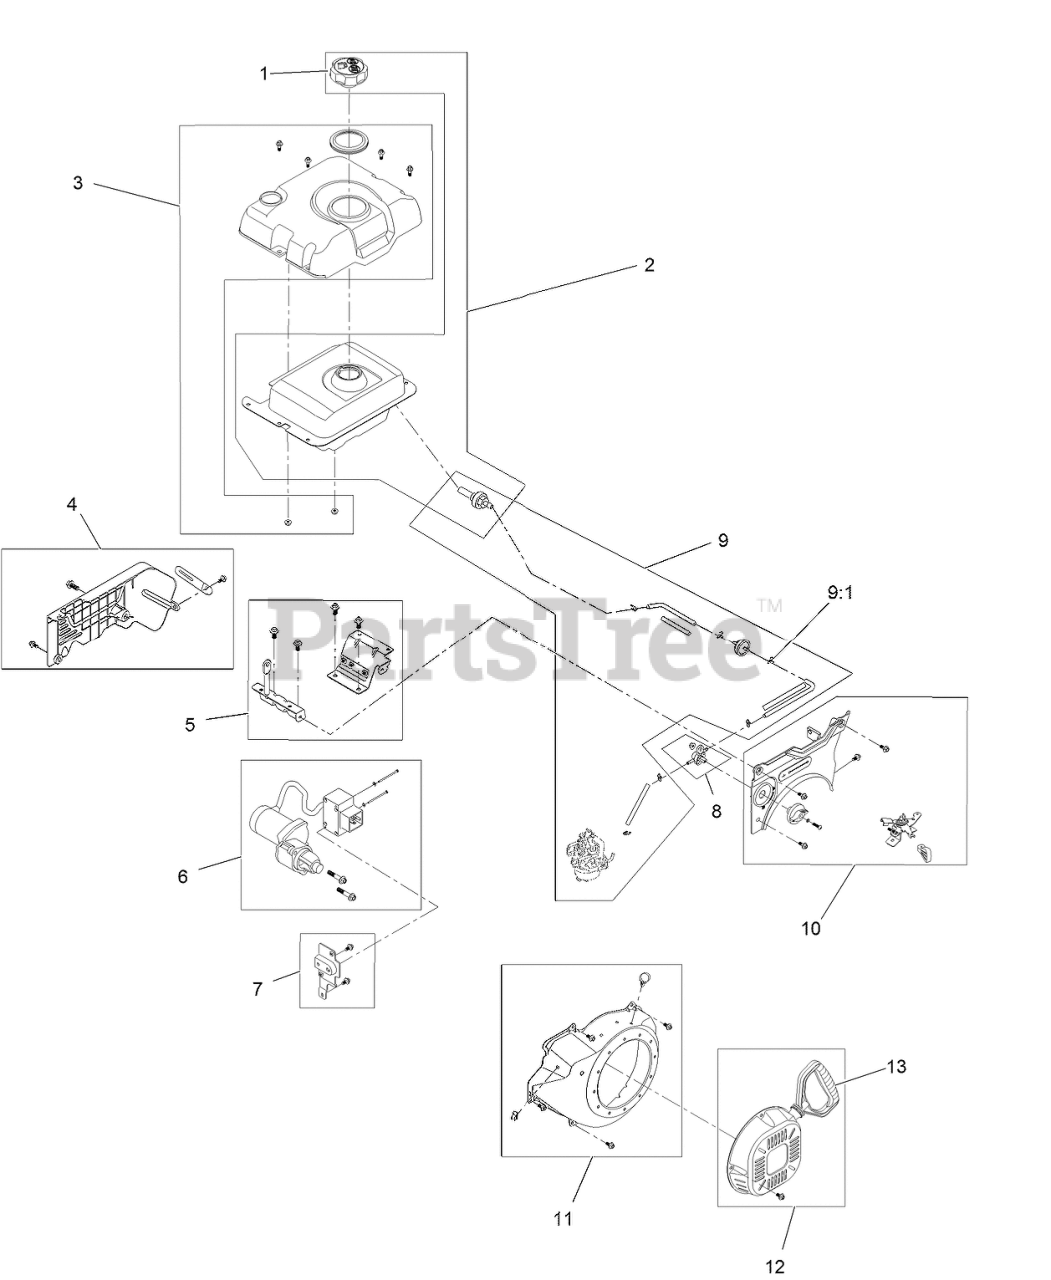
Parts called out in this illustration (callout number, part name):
1	CAP-FUEL
2	FUEL TANK AND CAP KIT
3	FUEL TANK COVER KIT
4	REAR PANEL AND HARDWARE KIT
5	TANK MOUNT BRACKET KIT
6	STARTER KIT
7	SWITCH BOX BRACKET KIT
8	FUEL SHUT-OFF VALVE KIT
9	COMPLETE FUEL LINE KIT
9:1	CLAMP-HOSE
10	FRONT PANEL KIT
11	RECOIL SHROUD KIT
12	RECOIL KIT
13	HANDLE-RECOIL
